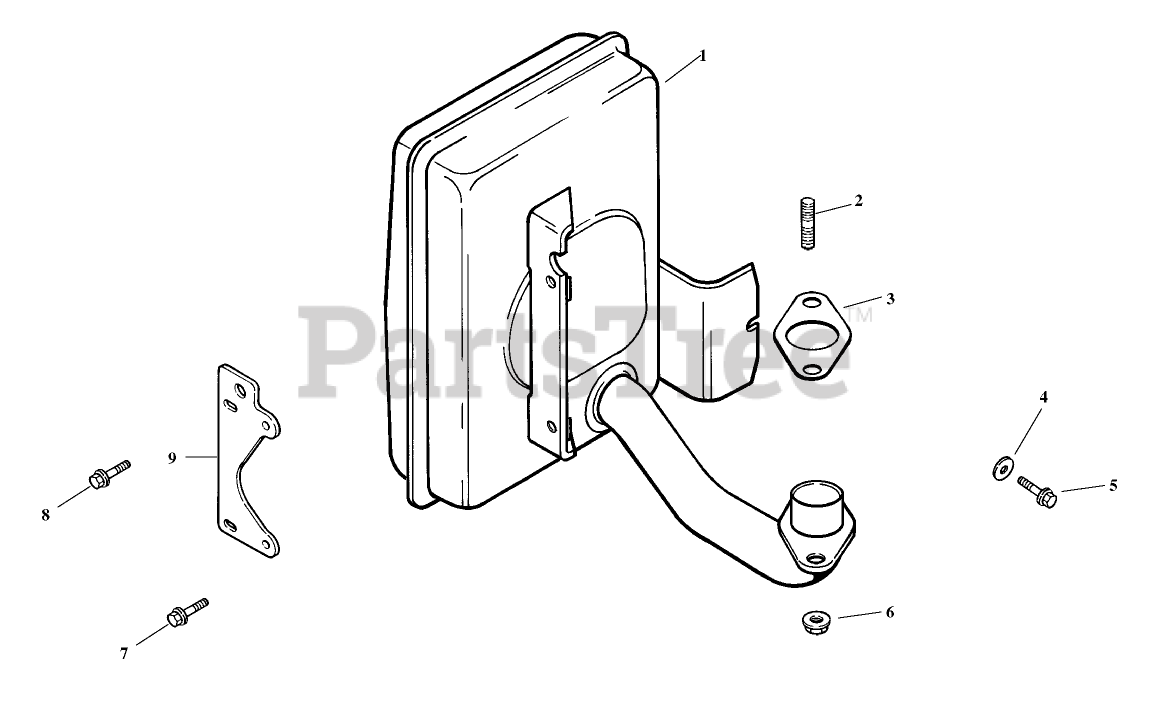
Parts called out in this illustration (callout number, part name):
1	Muffler
2	STUD (M8X1.25X33)
3	Gasket-Manifold, Exhaust
4	Washer-Plain (1/4in)
5	SCREW-FLANGE, THREAD FORMING (M5X0.8X16)
6	NUT-FLANGE (M8X1.25)
7	SCREW-FLANGE, THREAD FORMING (M6X1.0X16)
8	SCREW-FLANGE, THREAD FORMING (M6X1.0X25)
9	Bracket-Muffler
